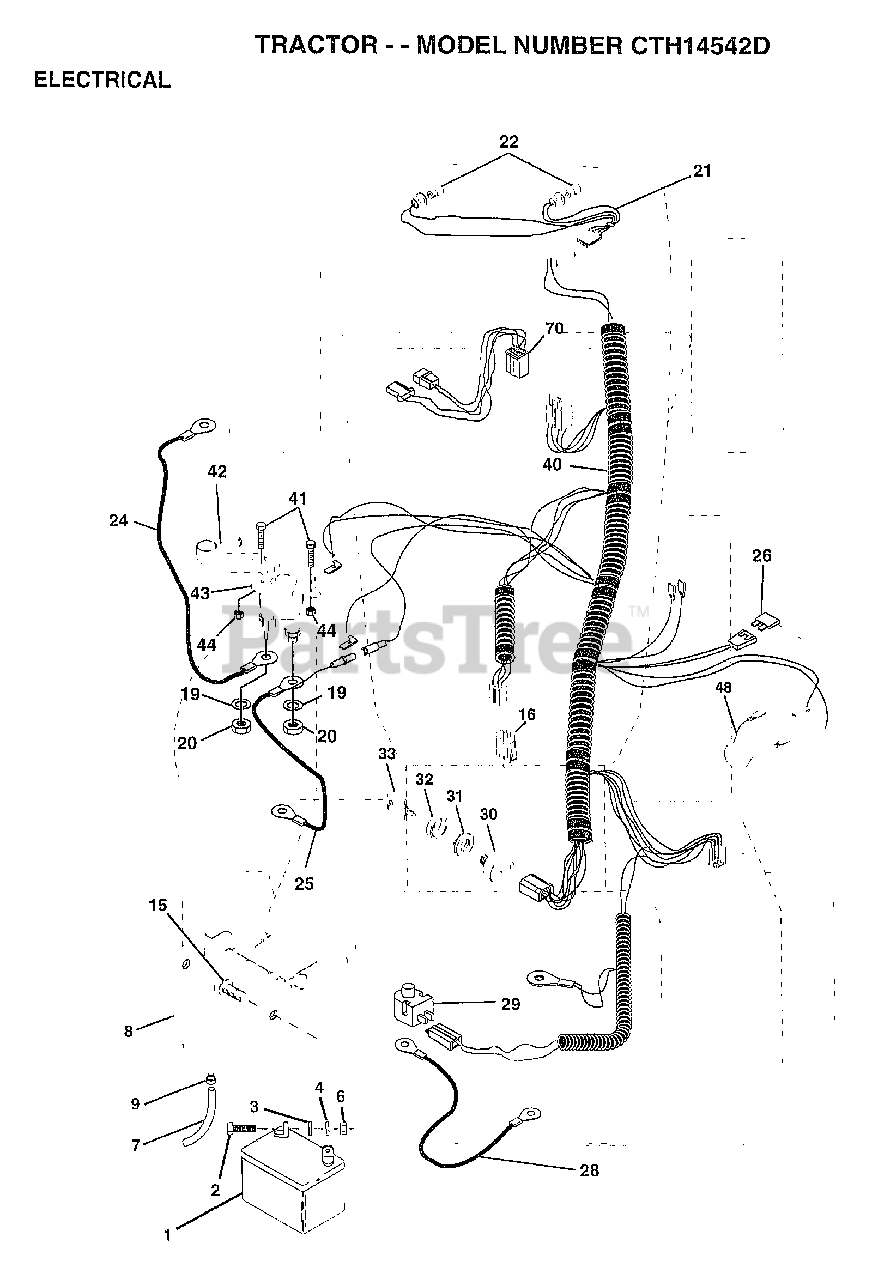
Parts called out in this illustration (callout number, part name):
2	BOLT LT
3	WASHER
4	LOCKWASHER
7	TUBE T
8	"CASE,BATTERY.MECH"
9	HOSE CLAMP T
15	FASTNER.SNAP-IN
16	SWITCH INTERLOCK
20	NUT
21	"HARNESS,LIGHT SOC"
22	HEADLAMP BULB
24	CABLE.BTRY.6GA.38
25	CABLE.BTRY.6GA.RD
26	FUSE HYT
28	CABLE T
29	SWITCH SEAT
30	SWITCH IGN 4POS
31	NUT IGNITION
32	COVER KEY SWITCH
33	KEY
40	HARNESS IGNITION
41	BOLT HXHD FIN
44	NUT HXKEP 1/4X20
48	ADAPTER AMMETER
70	HARNESS.ENG.DUAL
